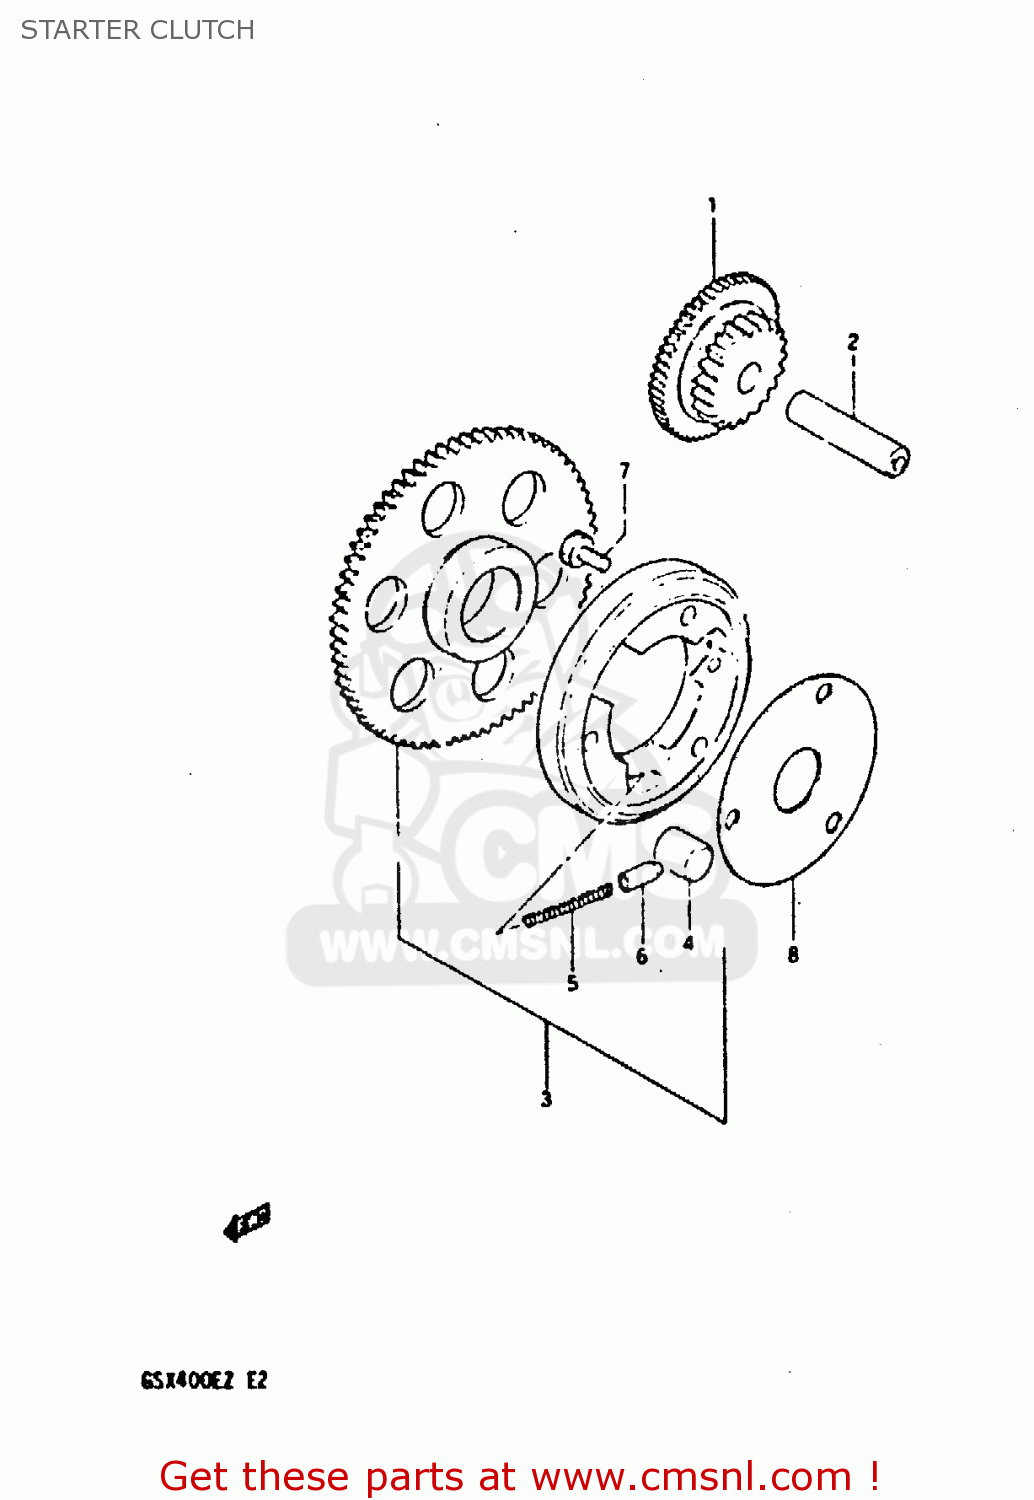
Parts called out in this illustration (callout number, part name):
1	GEAR,STARTER IDLE
2	PIN(7.4X13X56)
3	CLUTCH SET,STARTER
4	ROLLER(15X13)
5	SPRING
6	PIECE,PUSH
7	BOLT
8	SHIM,STARTER CLUTCH HUB
